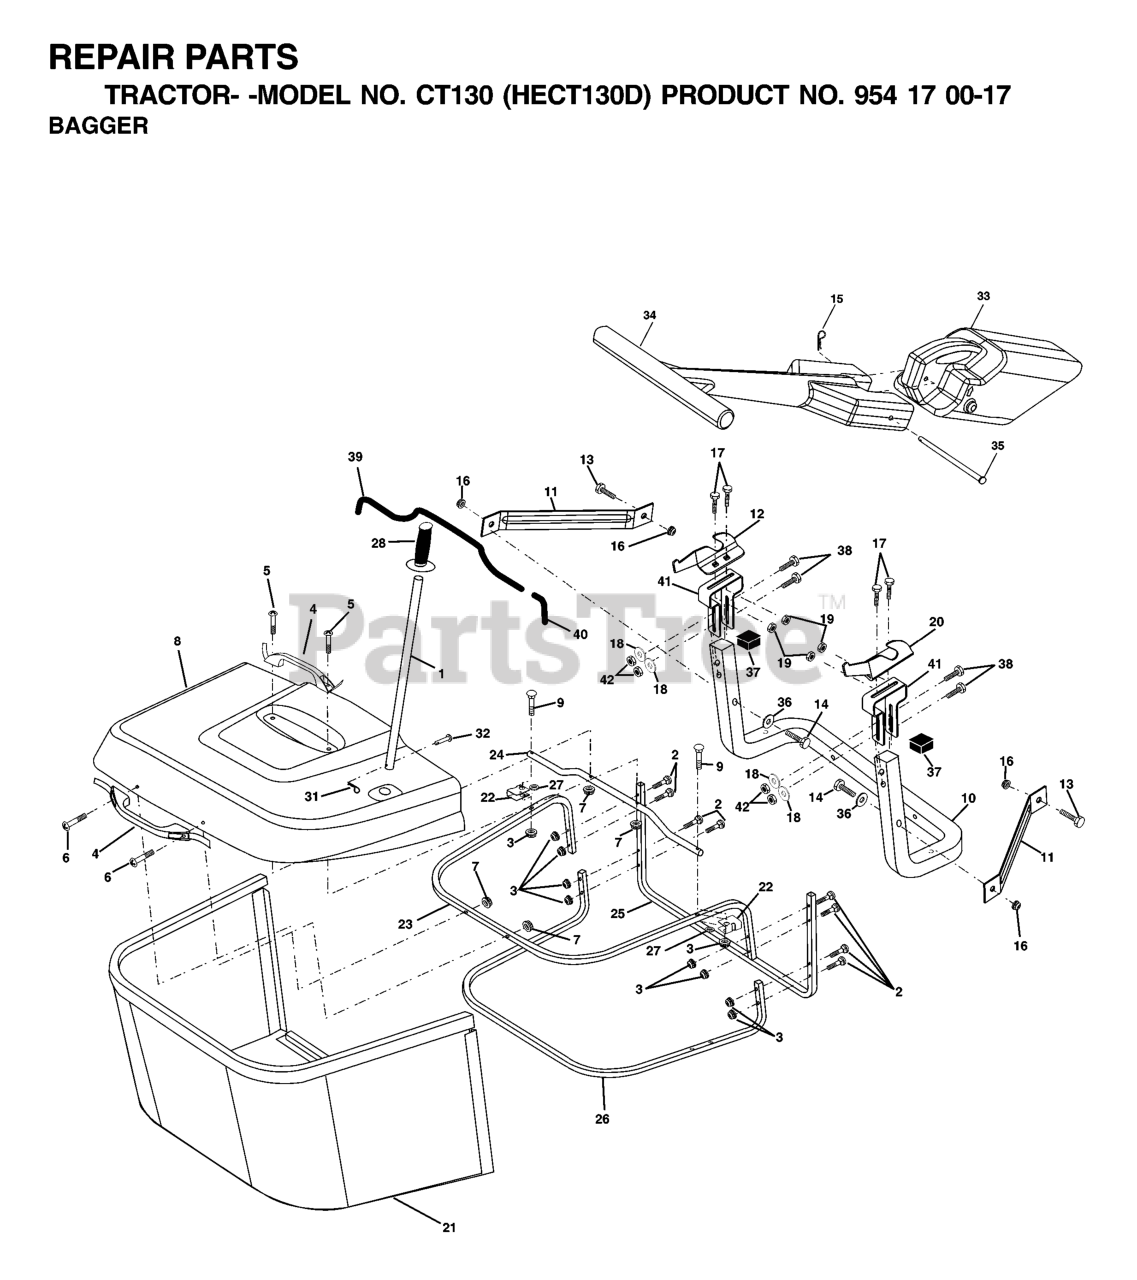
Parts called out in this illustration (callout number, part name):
1	TUBE HANDLE BAGGER
2	Bolt Carriage 1/4-20 x 2.0 Gr.5
3	NUT T
4	HANDLE.BAGGER.W/LVRS.BLK.CRD
5	SCREW.PAN.HEAD
6	REPL BY 532 75 00-29
8	COVER
9	Bolt Carriage 1/4-20 x 2.25d x Gr.5
10	TUBE
11	BRACKET.SUPPORT.UPPER.BAG.CRD
14	Bolt Hex 3/8-16 x 2-1/2 Gr. 5
15	RETAINER-SPRNG RB
16	NUT LOCK FLG 3/8-16 UNC
17	RP BOLT 5/16-18 X3/4 ZN/YEL GR
18	WASHER M
19	NUT LOCK HEX FLANGE 5/16-18
20	BRACKET
21	BAG
22	BRKT.SIDE.BAG.CRD
23	TUBE.UPPER.BAG.CRD
24	TUBE.PIVOT.BAG.CRD.BLACK
26	TUBE.LOWER.BAG.CRD
28	Grip Handle Black
31	RETAINER M
32	RIVET,DRILLED
33	PLUG.MULCHER.92 CRD
34	HANDLE.MULCHER.92.CRD (2 2)
36	WASHER
37	Plug Support Bagger CRD
38	BOLT.5/16-18X2.5
39	TRIM
40	TRIM
41	BRKT.VERT.ADJ.BAGGER.CRD
42	NUT.71038.31-18.HEX.NYLOCK
